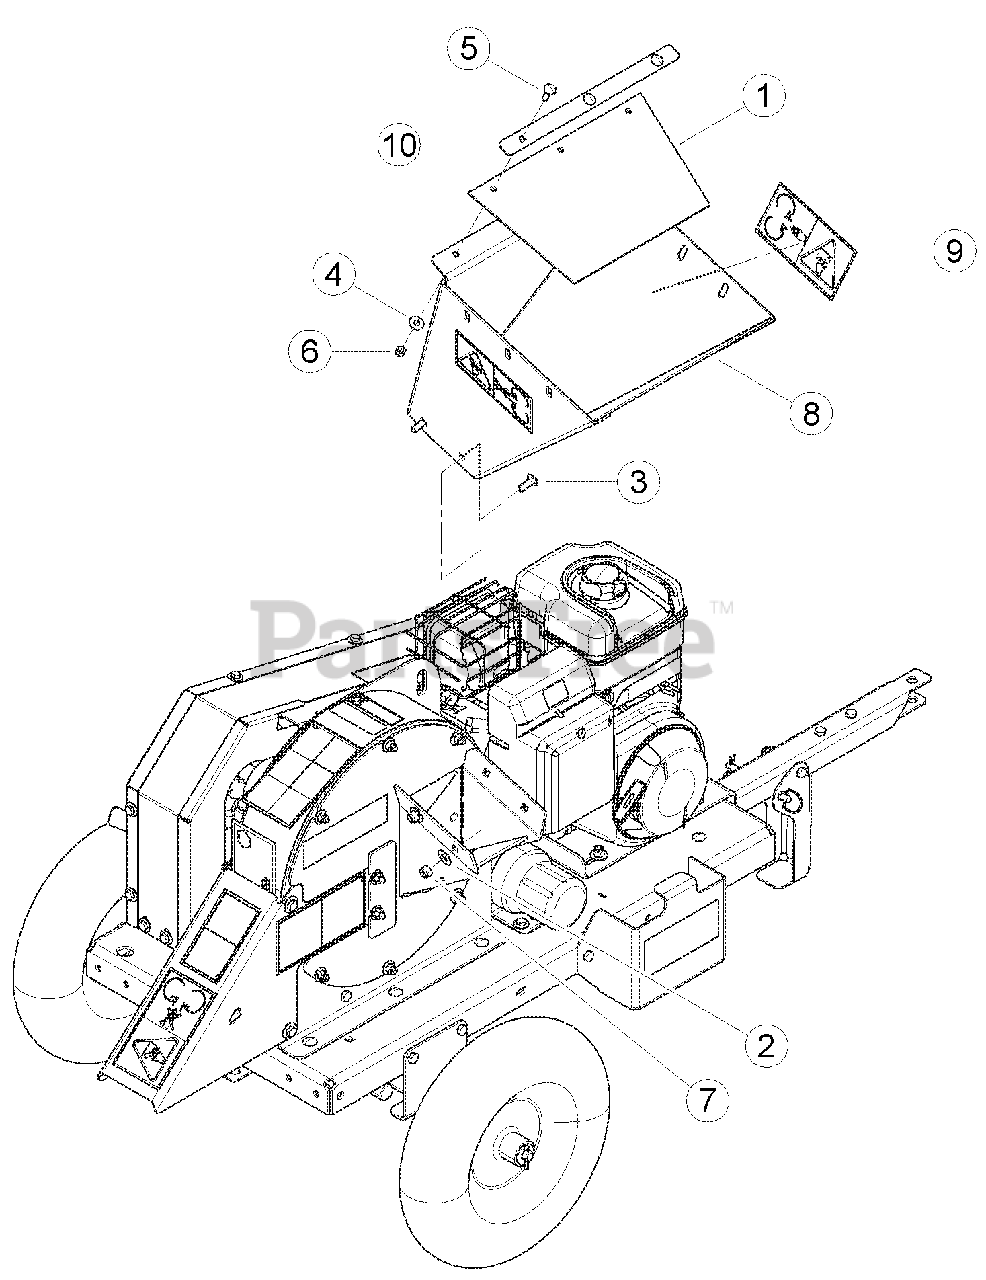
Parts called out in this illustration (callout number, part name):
1	FLAP, CHIPPER CHUTE
2	WASHER, 3/8 FLAT ZP
3	BOLT, 3/8 X 1 CRG GR5 NC ZP
4	WASHER, 5/16 FLAT ZP
5	BOLT, 5/16 X 1 CRG GR5 ZP
6	NUT, 5/16 NE NYLOCK ZP
7	NUT, 3/8 NE NYLOCK ZP
8	ASSEMBLY, HOPPER, SERVICE PART
9	DECAL, BLADE DANGER ISO
10	STRIP, FLAP RETAINER
